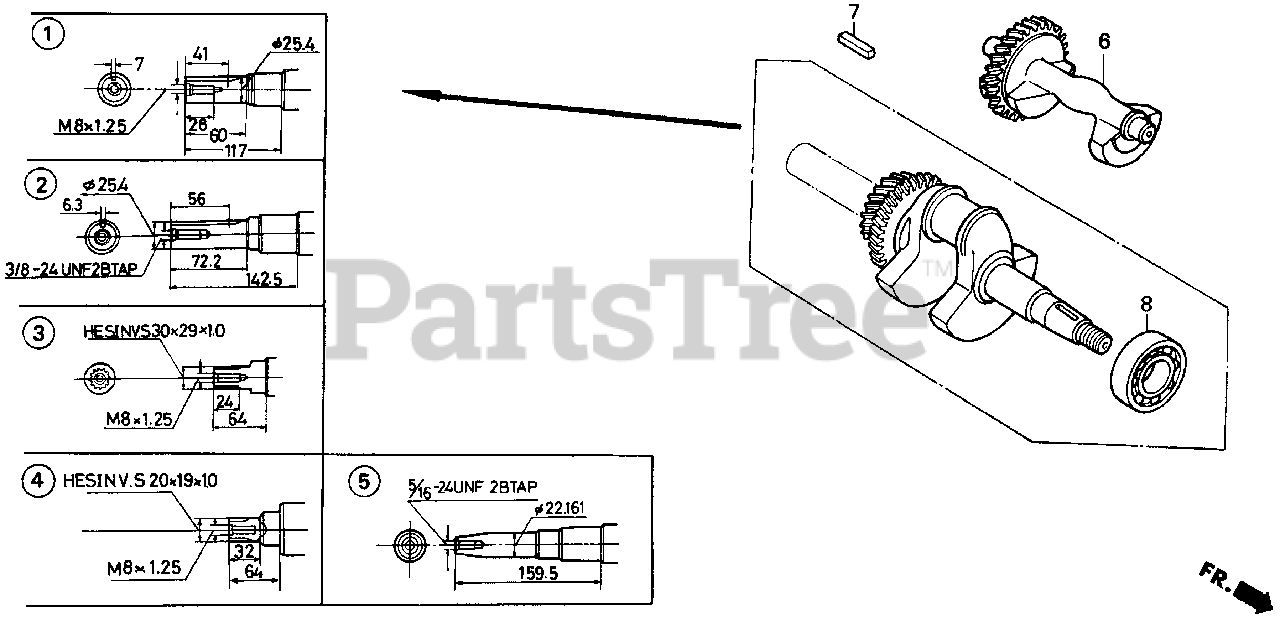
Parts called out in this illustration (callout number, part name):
5	CRANKSHAFT (V-TYPE)
6	WEIGHT, BALANCER
8	BEARING, RADIAL BALL (6207)
